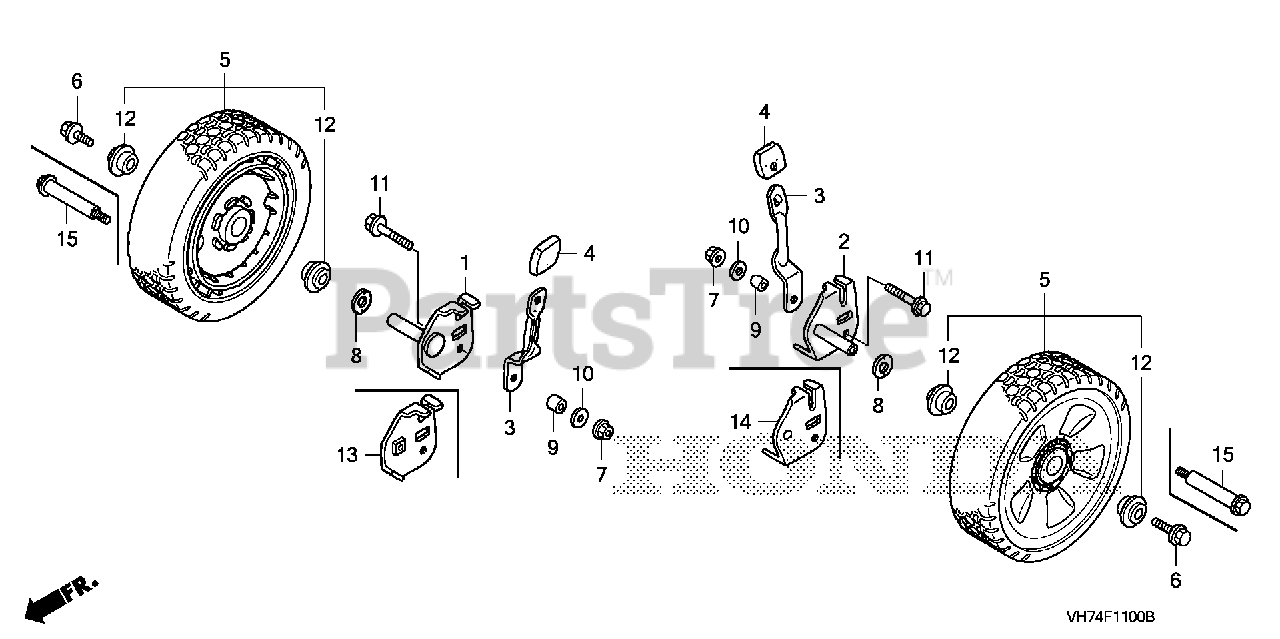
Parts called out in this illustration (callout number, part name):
3	PLATE, FR. ADJUSTER
4	GRIP, ADJUSTER *NH105* (MAT BLACK)
5	WHEEL, FR. *NH164* (GRIP GRAY)
7	NUT, SELF-LOCK (8MM)
7	NUT, FLANGE (8MM)
8	WASHER, WHEEL
9	COLLAR, FR. ARM
10	WASHER, PLAIN (8MM)
11	BOLT, SPECIAL (8X50)
12	BEARING, WHEEL
13	ARM, R. FR. ADJUSTER
14	ARM, L. FR. ADJUSTER
15	BOLT, FR. WHEEL SHAFT
